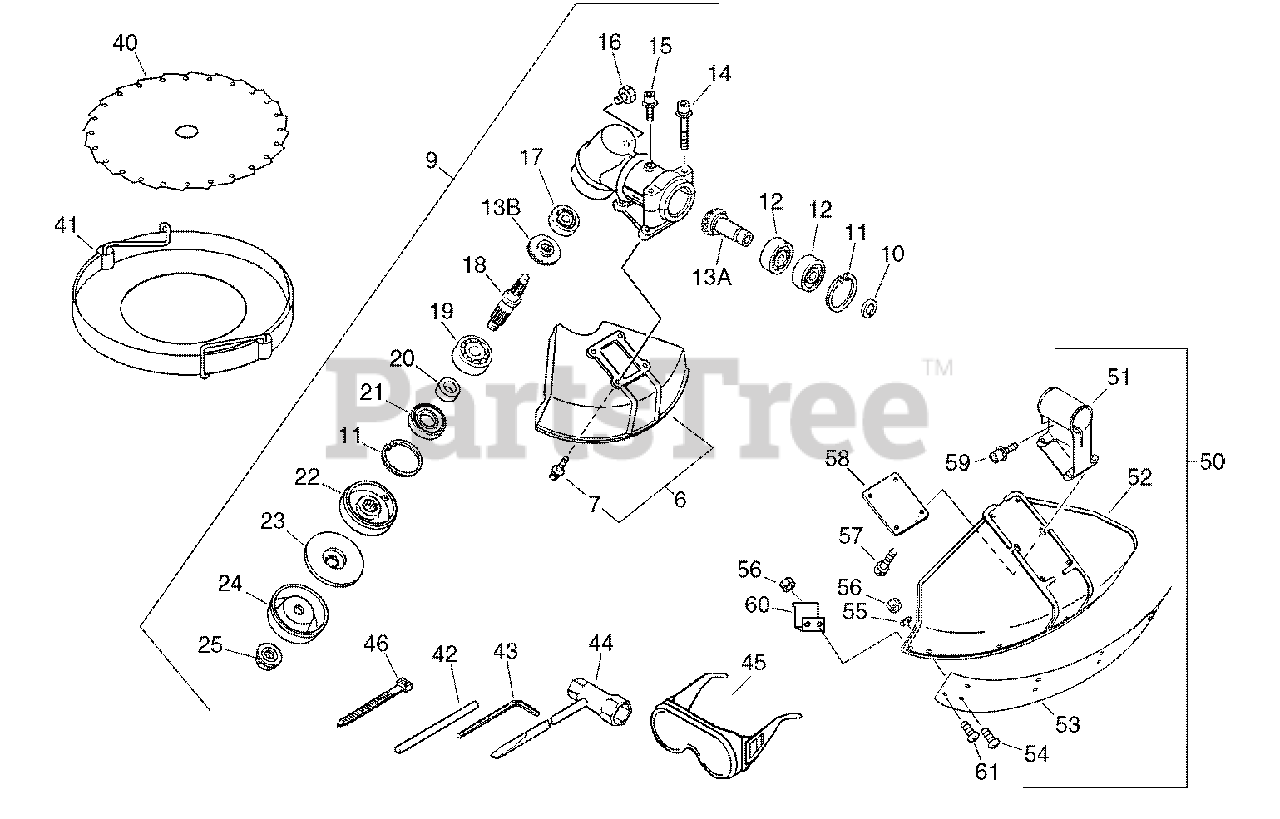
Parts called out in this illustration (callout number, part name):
6	DEBRIS SHIELD KIT
7	BOLT 5×20
9	GEAR CASE ASSY
10	RING, RETAINING 15
11	RING, SNAP 35
12	BEARING, BALL 6202
13	GEAR SET
14	BOLT M5×35
15	BOLT 5×14
16	BOLT M8×8
17	BEARING, BALL 6001
18	GEAR, SHAFT
19	BEARING, BALL 6202
21	SEAL, OIL
22	PLATE, ADAPTER - UPPER
25	NUT, LOCK
40	BLADE
41	COVER - GRAY
42	TOOL, LOCKING 5×120 MM
43	WRENCH, ALLEN 4 MM
44	T-WRENCH
45	GLASSES, SAFETY
46	STRAP, TIE
50	SHIELD ASSY
51	BRACKET, SHIELD
52	SHIELD, DEBRIS
53	EXTENSION, SHIELD
54	BOLT 5×14
55	WASHER 5.5×12×0.8
56	NUT M5
57	BOLT 5×18
58	BRACKET, SHIELD
59	BOLT 5×25
60	CUTTER, LINE
61	BOLT 5×12
